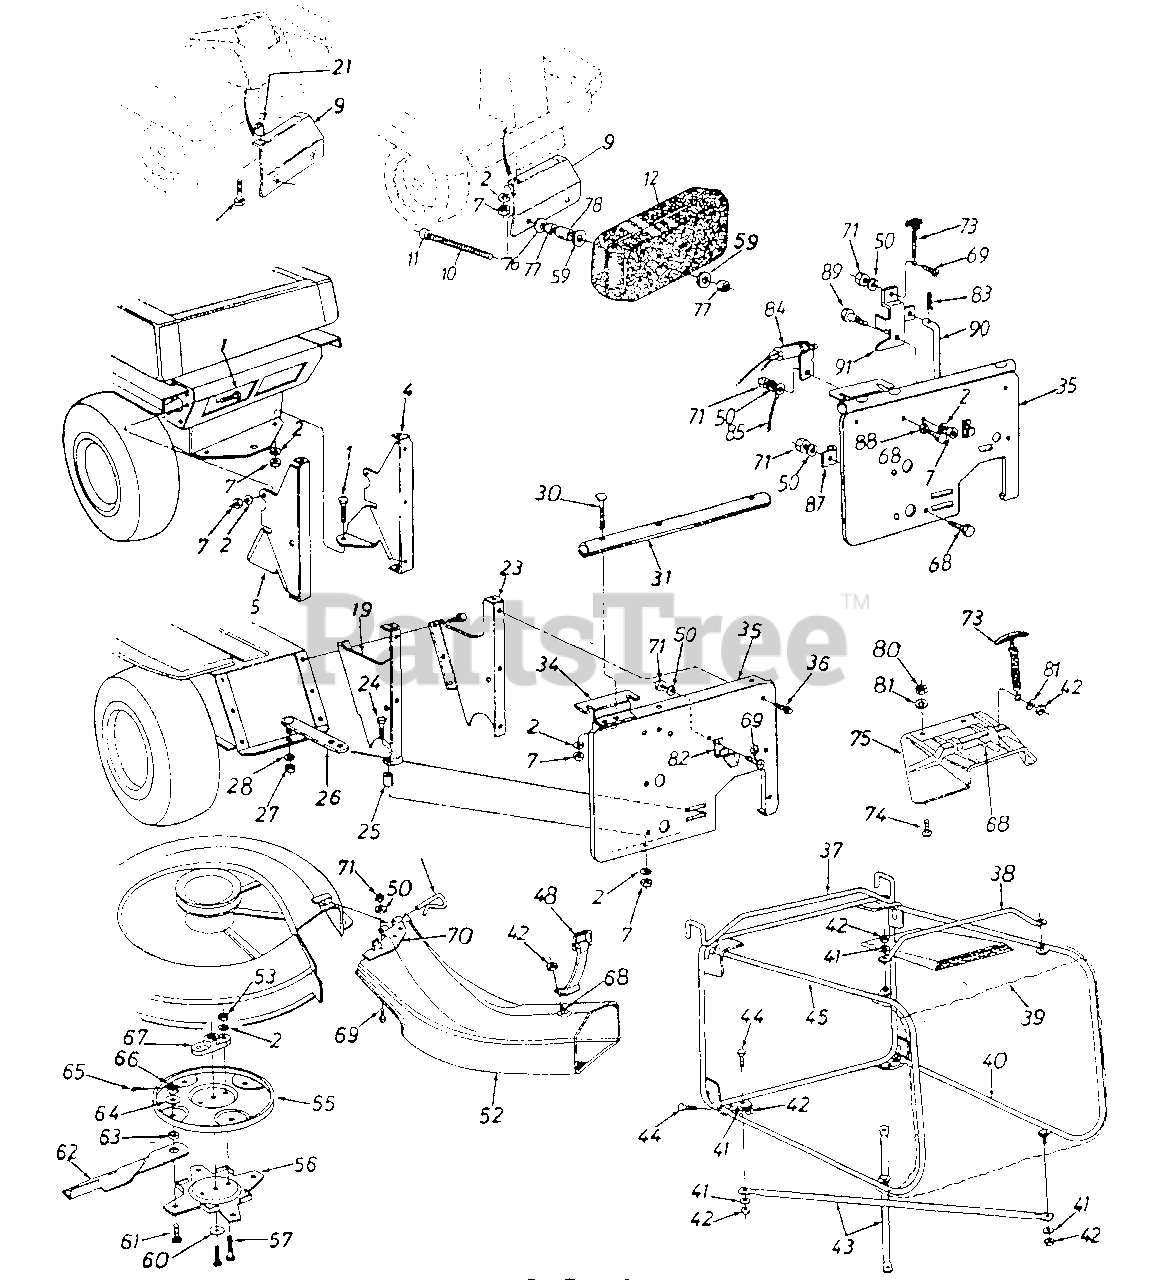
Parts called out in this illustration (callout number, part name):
1	Hex Bolt 5/16-1 x 1" Lg.
2	L-Wash. 5/16" I.D.
4	Catcher Support Brkt.-R.H.
5	Catcher Support Brkt.-L.H.
7	Hex Nut 5/16-18 Thd.
11	Hex Nut 7/16-14 Thd.
12	Counterweight 38 Lbs.
19	Catcher Support Brkt.-L.H.
21	Spacer .380" I.D. x 1" O.D. x .32" Lg.
23	Catcher Support Brkt.-R.H.
24	Hex Bolt 5/16-18 x 1.5" Lg.
25	Spacer .38" I.D. x .47" O.D. x 1" Lg.
28	L-Wash. 1/2" I.D.
30	Curved Carriage Bolt 5/16-18 x 1.75" Lg.
36	Hex Wash. Hd. Self-Tap Scr. 1/4-20 x .5" Lg.
42	Hex L-Nut 1/2-20 Thd.
43	Bottom Cross Brace
44	Hex Bolt 1/4-20 x .62" Lg.
50	L-Wash. 1/4" I.D.
52	R.D. Banana Chute Ass'y.
53	Hex Nut 5/16-24 Thd.
55	Upper Blade Disc
59	Fl-Wash. .45" I.D.
60	Bell-Wash. .39" I.D. x 1.38"
61	Shld. Bolt .50" Dia. x .36" (spec.)
62	30" Blade Tip
63	Spacer .505" I.D. x .75" O.D. x 1.25" Lg.
64	Fl-Wash. .5" I.D. x 1.25" O.D.
65	Cotter Pin 3/32" Dia. x 1" Lg.
66	Hex Slotted Nut 1/2-20 Thd.
67	Blade Adapter
68	Hex Bolt 1/4-20 x .5" Lg.
69	Truss Mach. Scr. 1/4-20 x .5" Lg.
73	Hook Latch Ass'y.
74	Truss Mach. Scr. 1/4-20 x .50"
75	R.D. Chute Extension
76	Bell-Wash. 7/16" I.D. x 1.25" O.D.
77	Hex Nut 7/16-14 Thd.
78	Spacer
81	Fl-Wash. .281" I.D. x .5" O.D.
82	Retainer Hook Brkt.
83	Int. Cotter Pin
84	Safety Switch (N.C.)
85	Electric Wire
87	Clamp
88	Ext. L-Wash. 1/4" I.D.
89	Shoulder Bolt
91	Switch Brkt.
